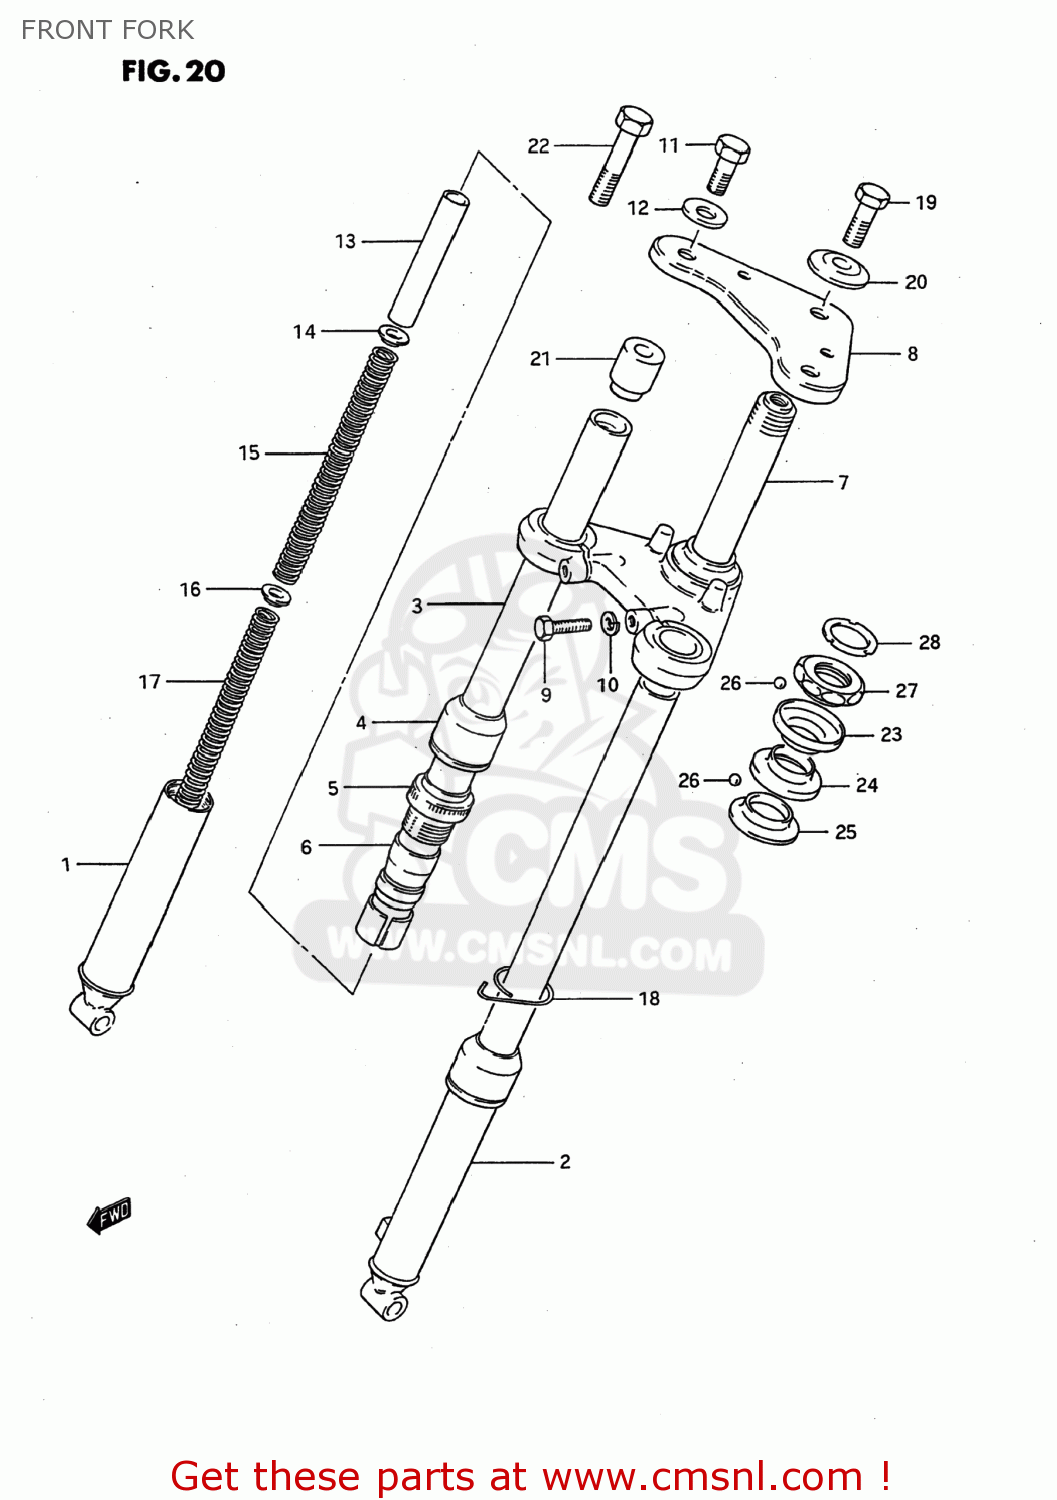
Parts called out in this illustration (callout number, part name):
1	TUBE,OUTER,R
2	TUBE,OUTER,L
3	TUBE,INNER
4	SEAL,DUST
5	NUT,OUTER
6	STOPPER
7	STEM,STEERING
8	HEAD,STEERING STEM
9	BOLT
10	WASHER,LOCK
11	BOLT
12	WASHER,STEERING STEM HEAD
13	SPACER
14	GUIDE,SPRING
15	SPRING,NO.1
16	GUIDE,SPRING NO.2
17	SPRING,NO.2
18	CLIP
19	BOLT
20	WASHER(33.5X10.5X4.2)
21	SPACER,FR FORK INNER TUBE
22	BOLT,FRONT FORK INNER TUBE
23	RACE,STEERING,INNER,UPPER
24	RACE,STEERING,INNER,LOWER
25	RACE,STEERING,OUTER,LOWER
26	BALL
27	RACE,STEERING,OUTER,UPPER
28	NUT
